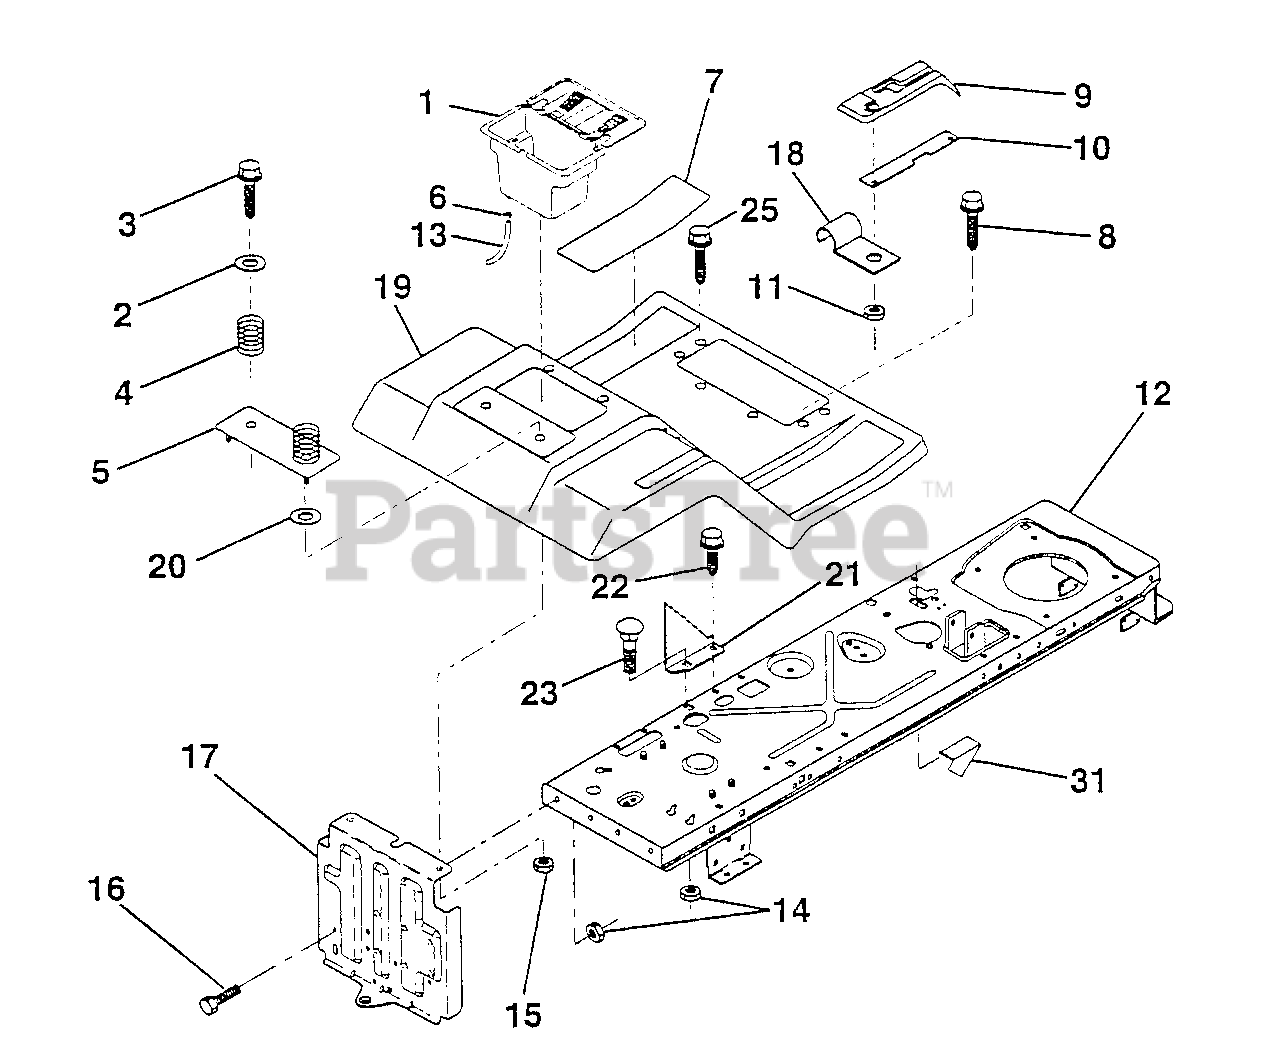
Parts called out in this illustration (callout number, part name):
1	Case Asm. Battery
2	Washer 13/32 x 1-1/4 x 12 Ga.
3	Screw Thdrol. 3/8-16 x 3/4
4	Spring seat
5	Plate Asm. Pnt Battery Fender
6	Clamp Hose Olive
7	Pad Footrest Rubber Deluxe
8	Screw Thdrol. 5/16-18 x 3/4
9	Console Shf. 6sp W/Ign.
11	Nut Self Thd. Wsh-Hd 1/4
12	Chassis Asm. Weldment
13	Tube Plastic
14	Nut Crownlock 5/16-18
15	Nut Keps Hex 1/4-20
16	Bolt Hex Hd. 5/16-18 x 3/4
17	Drawbar Asm.
18	Clip Insulated
19	Fend/Foot Asm. Pnt Shf. Fnd.
20	Washer 9/32 x 7/8 x 13 Ga.
21	Bracket Stop Depth
22	Screw Thdrol 5/16-18 x 1/2
23	Bolt Rdhdsqnk. 5/16-18 x 3/4
25	Scr-Hex Wsh Rol 5/16-18 x 1
30	Cap Spring
31	Switch Actuator
